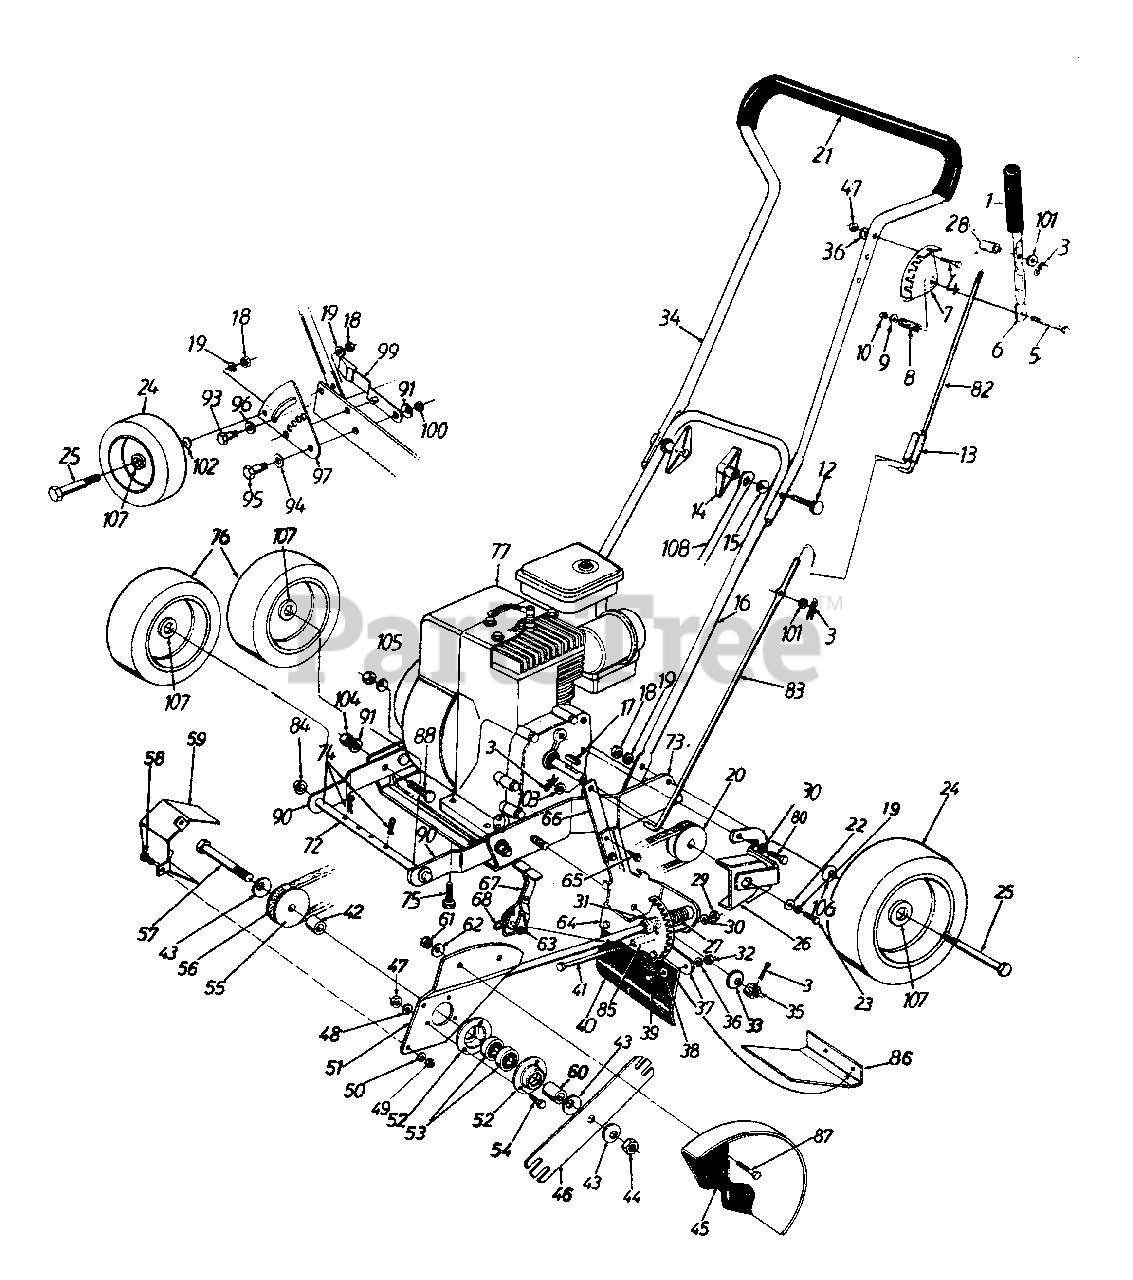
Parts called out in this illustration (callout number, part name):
1	Foam Grip
3	Cotter Pin 5/16" Dia.
4	Hex Bolt 1/4-20 x 1.25" Lg.
5	Hex Bolt 5/16-18 x 2" Lg.
8	Compression Spring 1.38" Lg.
9	Fl-Wash. .344" I.D.
10	Hex L-Nut 5/16-18 Thd.
12	Curv. Hd. Bolt 5/16-18 x 2" Lg.
13	Clutch Rod Lock
14	Wing Nut Ass'y.
15	Saddle Wash. .32" I.D. x .937"
18	Hex Nut 3/8-16 Thd.
19	L-Wash. 3/8" I.D.
20	Engine Pulley
21	Foam Grip
22	Fl-Wash. .835" I.D.
23	Hex Bolt 3/8-24 x 1" Lg.
24	Rear Wheel Ass'y.
25	Shoulder Bolt .498" Dia.
28	Ferrule
29	Hex Nut 5/16-18 Thd.
30	L-Wash. 5/16" I.D.
31	Spring Pin Spir. 1/4" Dia.
32	Hex Nut 1/4-20 Thd.
33	Bell-Wash. .535" I.D.
34	Upper Loop Handle
35	Hex Slotted Nut 1/2-20 Thd.
36	L-Wash. 1/4" I.D.
37	Flap Bracket
38	Fl-Wash. .25" I.D.
39	Hex Bolt 1/4-20 x .62" Lg.
41	Hex Bolt 5/16-18 x 4.5" Lg.
42	Spacer 1.030" Lg.
43	Bell-Washer. .63" I.D.
44	Hex Jam L-Nut 5/8-18 Thd.
47	Hex Nut 1/4-20 Thd.
48	L-Wash. 1/4" I.D.
49	Hex Nut 1/4-20 Thd.
50	L-Wash. 1/4" I.D.
53	Ball Bearing .62" I.D.
54	Hex Bolt 1/4-20 x .62" Lg.
55	3/8" "V"-Pulley
56	"V"-Belt
57	Hex Bolt 5/8-18 x 4.5" Lg.
58	Hex Bolt 1/4-20 x .625" Lg.
60	Sleeve .90" Lg.
61	Hex Nut 5/16-18 Thd.
62	Bell-Wash. .345" I.D.
63	Spring Pin Spir. 1/4" Dia.
68	Torsion Spring
72	Axle 8.20" Lg. (Front)
75	Hex TT-Tap Scr. 3/8-16 x 1" Lg.
76	Front Wheel Ass'y.
77	Engine
80	Hex Bolt 5/16-24 x .62" Lg.
82	Upper Clutch Rod
83	Lower Clutch Rod
84	Push Cap 1/2" Dia.
85	Spacer 3.765" Lg.
88	Ribbed Neck Bolt 3/8-24 x .8" Lg.
93	Shld. Bolt .5" Dia.
94	Bell-Wash. .515" I.D.
96	Fl-Wash. .51" I.D. x 1.0" O.D.
100	Hex Jam Nut 3/8-16 Thd.
101	Fl-Wash. .344" I.D. x .62" O.D.
102	Wave Wash. .51" I.D.
103	Fl-Wash. .406" I.D. x .81" O.D.
104	Hex Nut 3/8-24 Thd.
105	Bell-Wash. .396" I.D. x 1.14" O.D.
106	Bell-Wash. .38" I.D. x .88" O.D.
107	Ball Bearing
